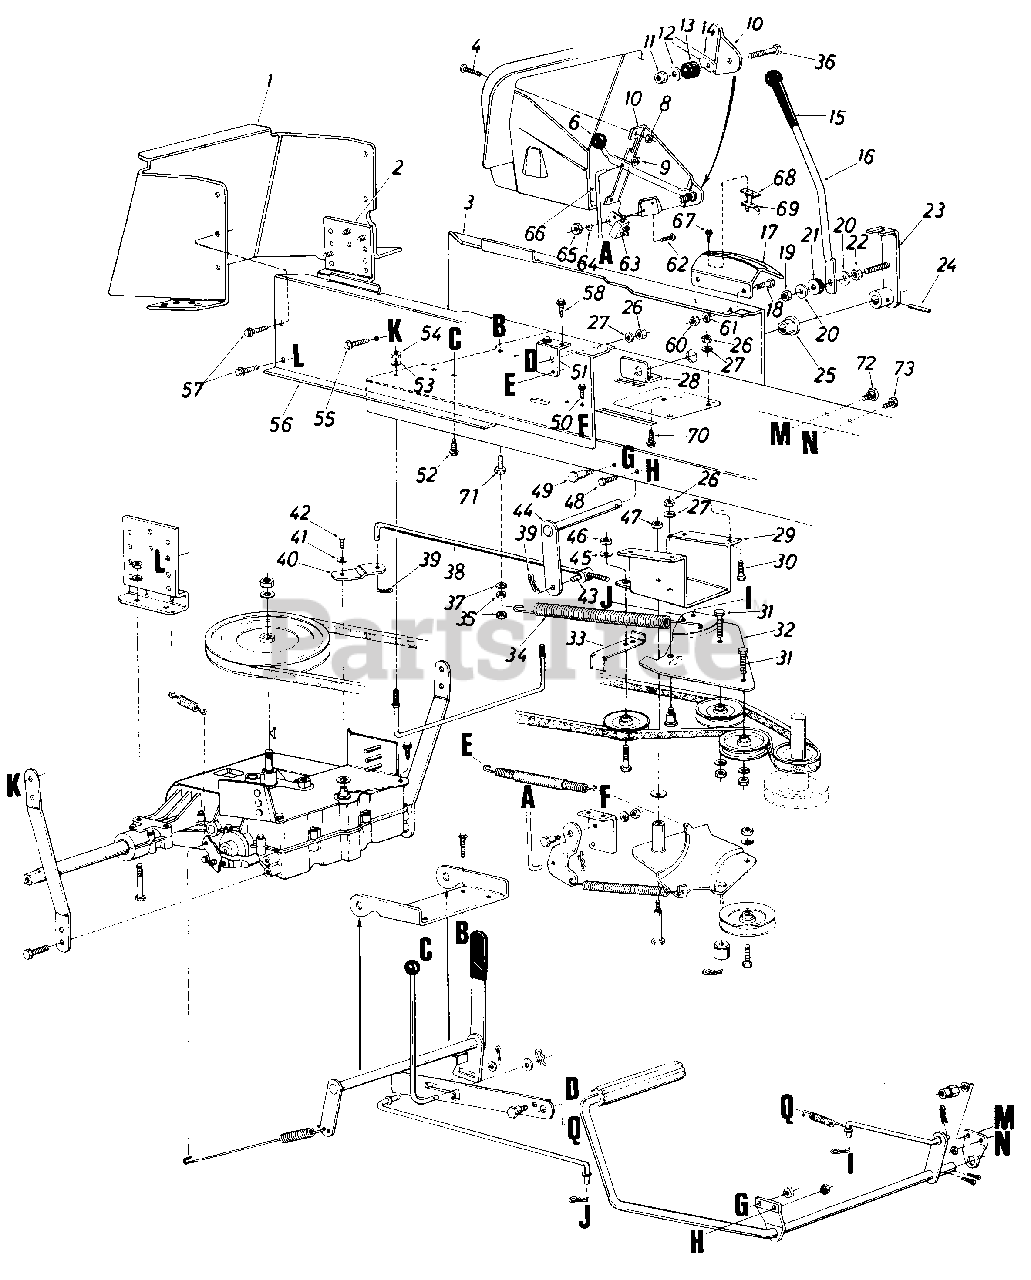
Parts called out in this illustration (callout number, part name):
1	Hitch Plate
2	Transaxle Support Bracket
3	Side Panel Upper Frame L.H.
4	Truss. Mach. Scr. 1/4-20 x .50" Lg
6	Ball Knob
8	Hex Sems Nut 1/4-20 Thd
9	Push Cap 1/4" Rod
10	Deck Clutch Control Brkt.
11	Hex Cent. L-Nut 1/4-20 Thd.
12	Fl-Wash. .281 " I .D. x .734" O.D. x .063 Thk.
13	Rubber Wash. .330" I.D. x .87" O.D. x .32 Thk.
14	Blade Clutch Lever
16	Shift Lever
19	Hex Cent. L-Nut 5/16-18 Thd.
20	Fl-Wash. .344" I.D. x .875" O.D. x .063 Thk.
21	Rubber Wash. .330" I.D. x .87" O.D. x .32 Thk.
22	Hex Nut 5/16-18 Thd.
23	Handle Mount Brkt. Ass'y.
24	Spring Pin Spiral 1/4" Dia, x 1.5" Lg
25	Plastic Hex Bearing .625" I.D.
26	Hex Nut 5/16-18 Thd.
27	L-Wash. 5/16" I.D.
28	Speed Control Shaft Brkt.
29	Transaxle Clutch Support Brkt.
30	Hex Bolt 5/16-18 x 2.50" Lg.
31	Hex Bolt 3/8-16 x 1.25" Lg.
32	Idler Bracket Ass'y.
35	Hex Cent. L-Nut 1/4-20 Thd.
36	Hex Bolt 1/4-20 x 1.25" Lg.
37	L-Wash. 1/4" l.D.
38	Shift Link
39	Hairpin Cotter 3/8"
40	Shifter Bracket
41	Belleville Wash. .25 I.D. x .375 O.D.
42	Hex Bolt 1/4-28 x .62 Lg.
43	Pivot Bushing
44	Speed Control Shaft Ass'y.
45	Fl-Wash. .385 I.D. x .87 O.D. x .060 Thk.
46	Hex Cent. L-Nut 3/8-24 Thd.
47	Hex Cent. L-Nut 3/8-16 Thd.
48	Hex Bolt 3/8-16 x .62 Lg.
49	Shoulder Bolt .500 Dia. x .340 Lg. (3/8-16)
50	Hex Thd. Rolling Scr. 1/4-20 x .50 Lg.
51	Parking Brake Cam Mtg. Brkt.
52	Hex Thd. Rolling Scr. 1/4-20 x .50 Lg.
53	L-Wash. 1/4" I.D.
54	Hex Nut 1/4-20 Thd.
55	Hex Wash. Hd. TT-Tap Scr. 3/8-16 x .5 Lg.
56	Side Panel Upper Frame-R.H.
57	Hex Thd. Rolling Scr. 5/16-24 x .50 Lg.
58	Hex Thd. Rolling Scr. 1/4-20 x .50" Lg
60	Hex Nut 5/16-18 Thd.
61	L-Wash. 5/16" I.D.
62	Truss Mach. Scr. #10-24 x .50 Lg.
63	Safety Switch
64	Ext. L-Wash. #10 I.D.
65	Hex Nut #10-24 Thd.'
66	Deck Control Rod
67	Hex Wash. Hd. Scr. #8 x .50 Lg.
68	Insulator Nut Plate
69	Spring Switch
70	Hex Wash. Hd. AB-Tap Scr. 5/16 x 75n Lg.
71	Hex Wash. Hd. TT-Tap Scr. 1/4 x 1.5 Lg.
72	Shld. Bolt .498 Dia. x .34
73	Hex Bolt 3/8-16 x .62 Lg.
